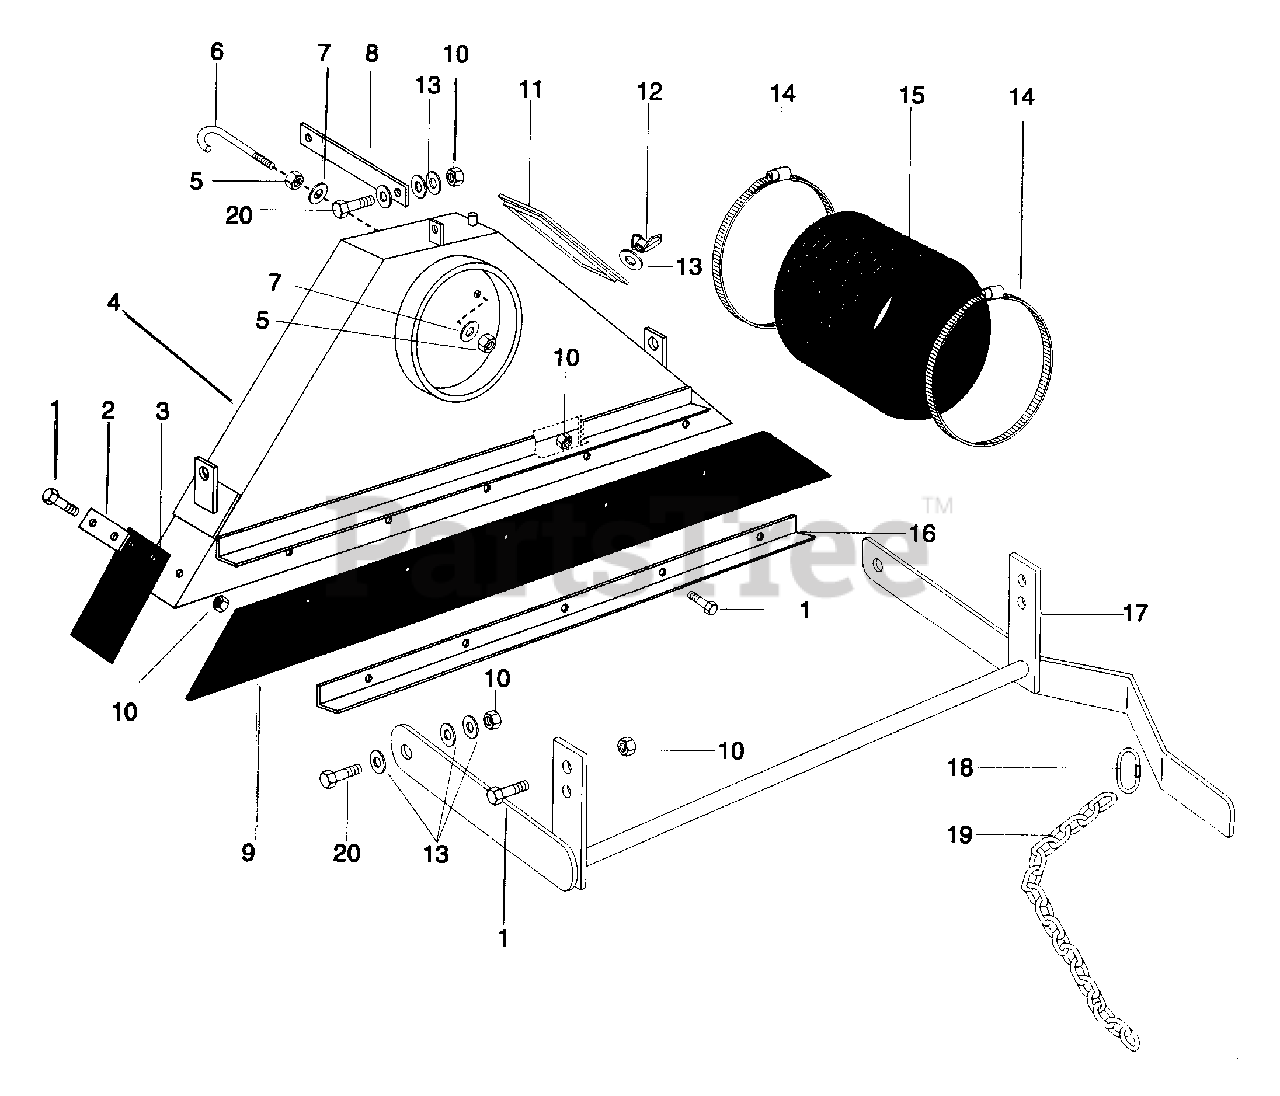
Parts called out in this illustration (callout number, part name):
1	Blt-Hex .38-16 x 1.00 Gr 5
2	End Bolting Strip
3	Flex Skirt Endcap
4	Scoop Weldment
5	Nut-Hex .50-13
6	J-Bolt
7	Wshr-Fl-Stl .563 x 1.38 x .109
8	Scoop Stabilizer Brace
9	Flex Skirt Front
9	Flex Skirt Rear
10	Nut-Lk-Ctr.38- 16
11	Scoop Side Cover
12	Nut-Wing .375-16 Pl
13	Wshr-Fl-Stl .438 x 1.00 x .083
14	Clamp
15	Flex Hose
16	Retainer Strip
17	Scoop Lift Weldment
18	1/4 Quick Link
19	10 Link 1/4 Chain
20	Blt-Hex .38-16 x 1.25 Gr 5
